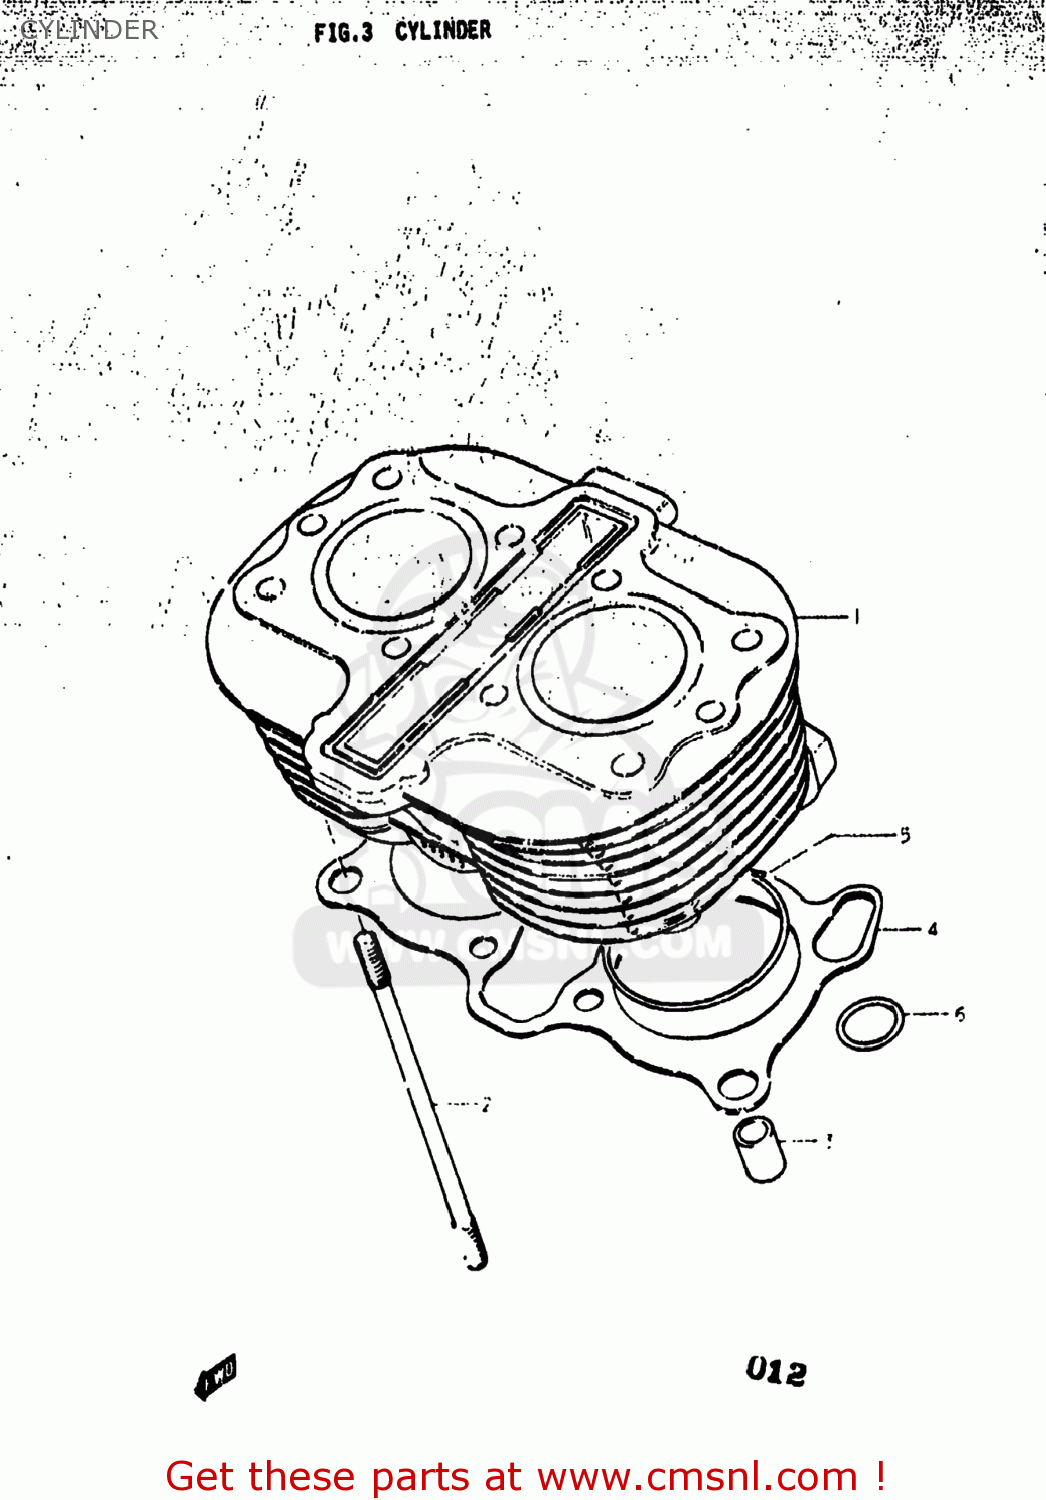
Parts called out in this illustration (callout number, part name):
1	CYLINDER
2	STUD
3	PIN
4	GASKET,CYLINDER (MCA)
5	O RING(D:2,ID:70)
6	O RING(D:3.05)
